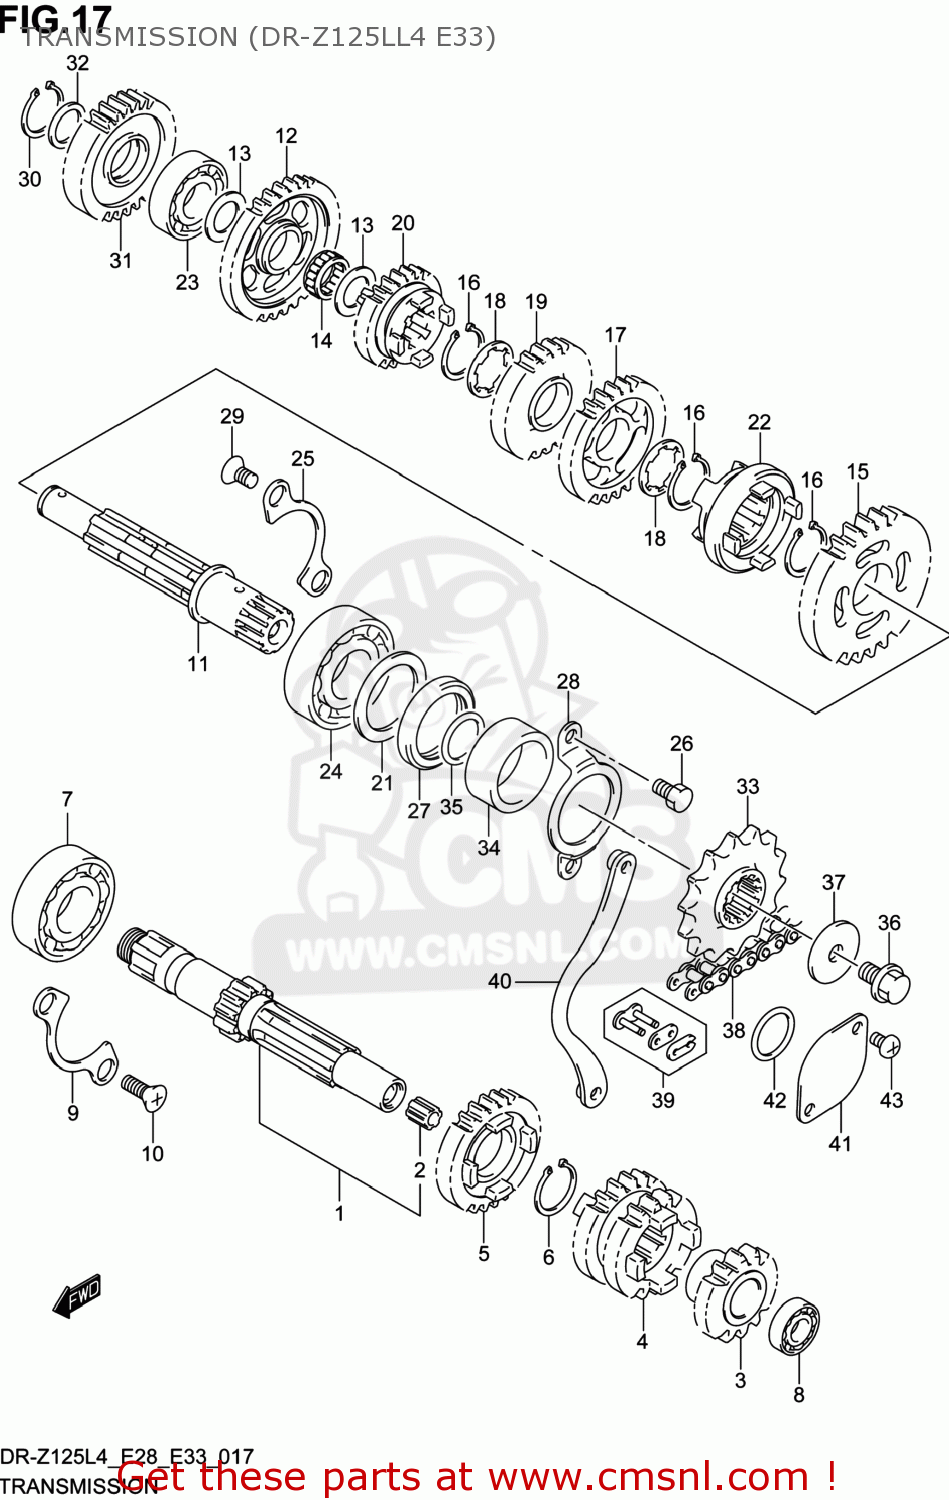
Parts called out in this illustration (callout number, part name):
1	SHAFT,COUNTER(NT:11)
2	BUSH
3	GEAR,2ND DRIVE(NT:14)
4	GEAR,3RD & 4TH DRIVEN(NT:19/21
5	GEAR,5TH DRIVE(NT:26)
6	CIRCLIP
7	BEARING(20X47X14)
8	BEARING
9	RETAINER,DRIVE SHAFT BEARING
10	SCREW(6X12)
11	SHAFT,DRIVE
12	GEAR,1ST DRIVEN(NT:33)
13	WASHER
14	BEARING(15X19X7.8)
15	GEAR,2ND DRIVEN(NT:26)
16	CIRCLIP
17	GEAR,3RD DRIVEN(NT:26)
18	WASHER,LOCK
19	GEAR,4TH DRIVEN(NT:23)
20	GEAR,5TH DRIVEN(NT:24)
21	WASHER,OIL SEALING
22	WHEEL,SLIDING DOG
23	BEARING(15X36X12)
24	BEARING(22X50X14)
25	RETAINER,DRIVE SHAFT BEARING
26	BOLT
27	SEAL,OIL(30X40X6)
28	RETAINER,DRIVE SHAFT OIL SEAL
29	SCREW(6X12)
30	CIRCLIP
31	GEAR,KICK STARTER IDLE(NT:26)
32	SHIM(15X20X1)
33	SPROCKET,ENGINE(14T)
34	SPACER,ENGINE SPROCKET
35	O RING(D:2.5,ID:21)
36	BOLT
37	WASHER
38	CHAIN,DRIVE
39	JOINT SET,CHAIN
40	PLATE,FR CHAIN GUIDE
41	CAP,NEUTRAL SWITCH HOLE
42	O RING(D:2.4,ID:21.8)
43	SCREW
